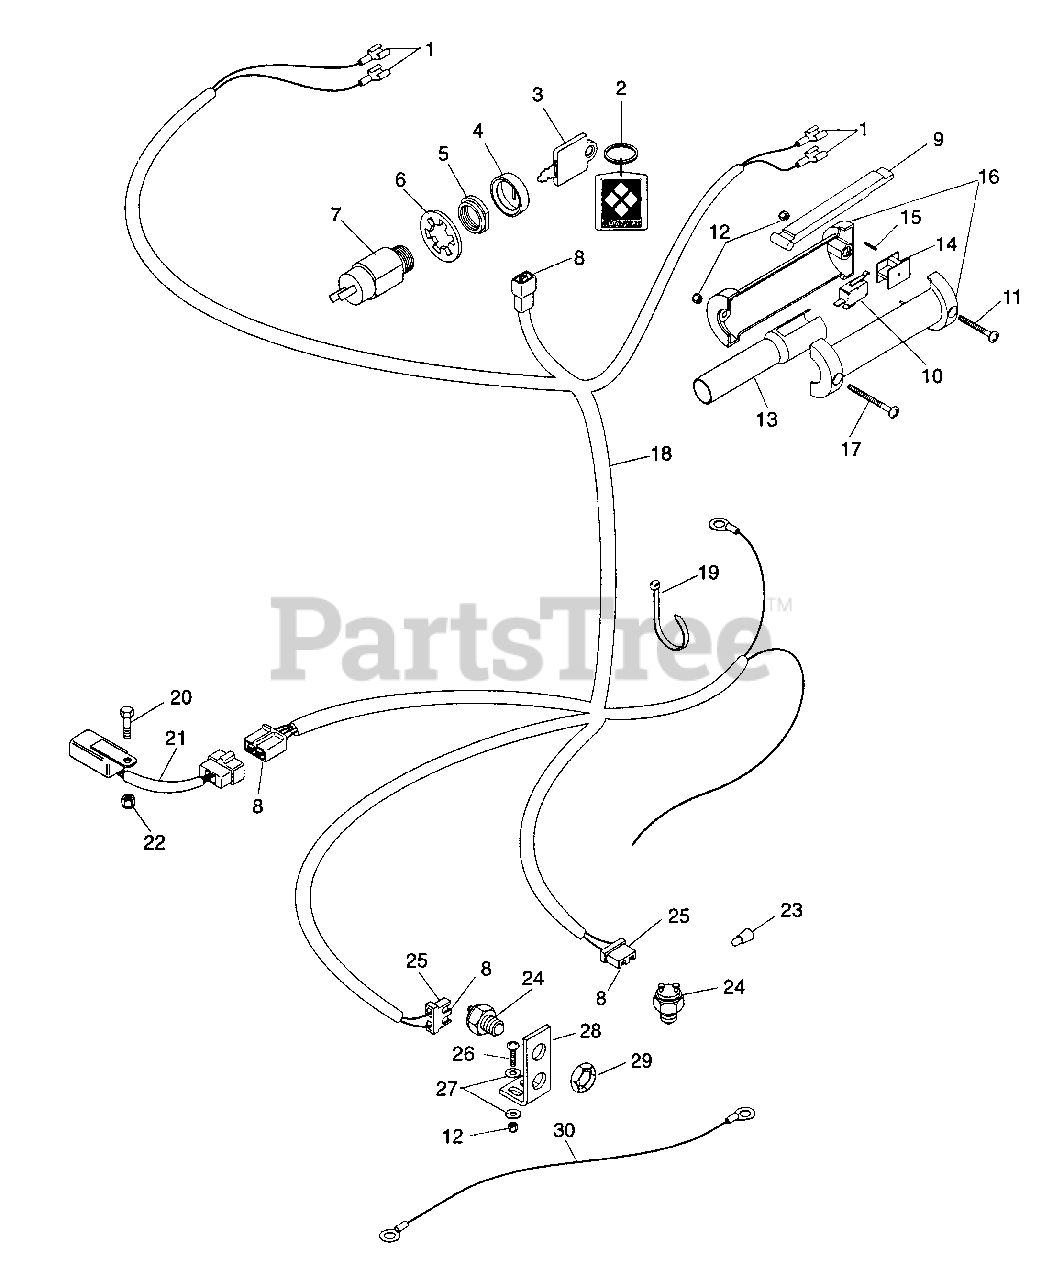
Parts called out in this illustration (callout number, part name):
1	Terminal, Female
2	Key Chain
3	Ignition Switch Key
4	Cap-Ignition Switch
5	Nut-Panel .625-32
6	Washer-Lock-Internal .625 x .045
7	Key Switch Assembly
8	Terminal
11	Screw-Machine 10-24 x .625
12	Nut-Locking 10-24
13	Insert, Handlebar
14	Holder, Switch
15	Pin-Roll .094 x .750
16	Handle Left Hand and Right Hand
17	Screw-Machine 10-24 x 1.50
18	Harness, Wiring Pro Recoil
19	Tie Wrap, Black
20	Bolt-Hex .25-20 x .75 Grade 5
21	Module
22	Nut-Locking-Nylon .250-20 Grade 2
23	Nut-Connector
24	Switch-Neutral Start N.C.
25	Connector, 2-Wire Switch
26	Screw-Machine 10-24 x .750
27	Washer-Flat-Steel .188 x .438 x .049
28	Bracket, Interlock Switch
29	Nut, Stamped .56-18
30	Wire, Ground
